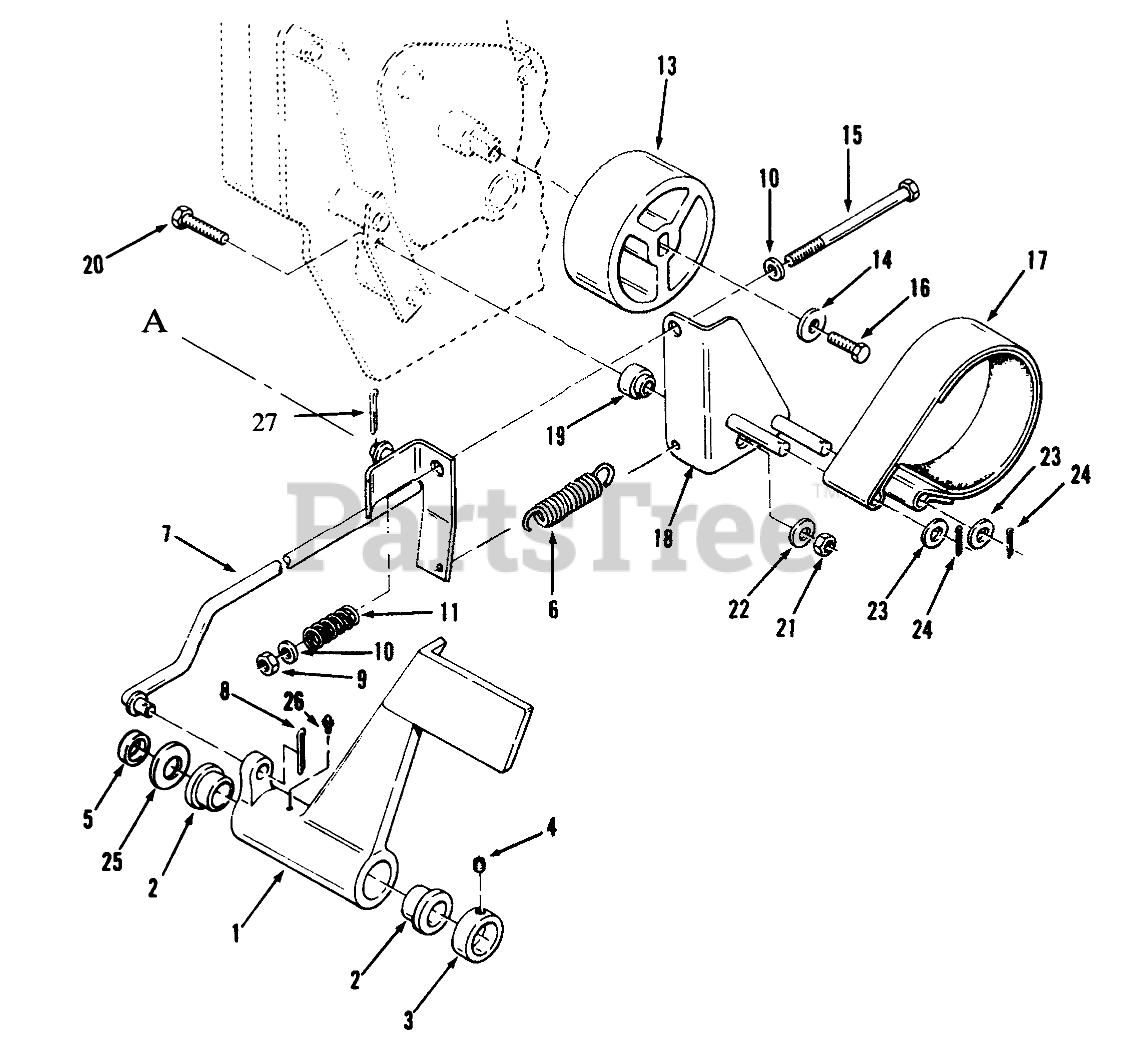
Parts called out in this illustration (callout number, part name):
1	Pedal-Brake
2	BUSHING
3	COLLAR
4	SCREW-HSH
5	SPACER
6	SPRING
7	ASY BRAK RD WAR
8	PIN-COTTER
9	NUT-LOCK, NI
10	WASHER-FLAT
11	SPRING-COMPRESSION
13	DRUM-BRAKE
14	WASHER
15	SCREW-HH
16	SCREW-HH, LOCK
17	ASSY-BRAKE BAND
18	WA-BRAKE PIVOT B
19	BUSHING-BRAKE PIVOT
20	SCREW-HH
21	NUT-LOCK, NI
22	WASHER-FLAT
23	WASHER-FLAT
24	PIN-COTTER
25	WASHER
26	FITTING-GREASE
27	PIN-HAIR
